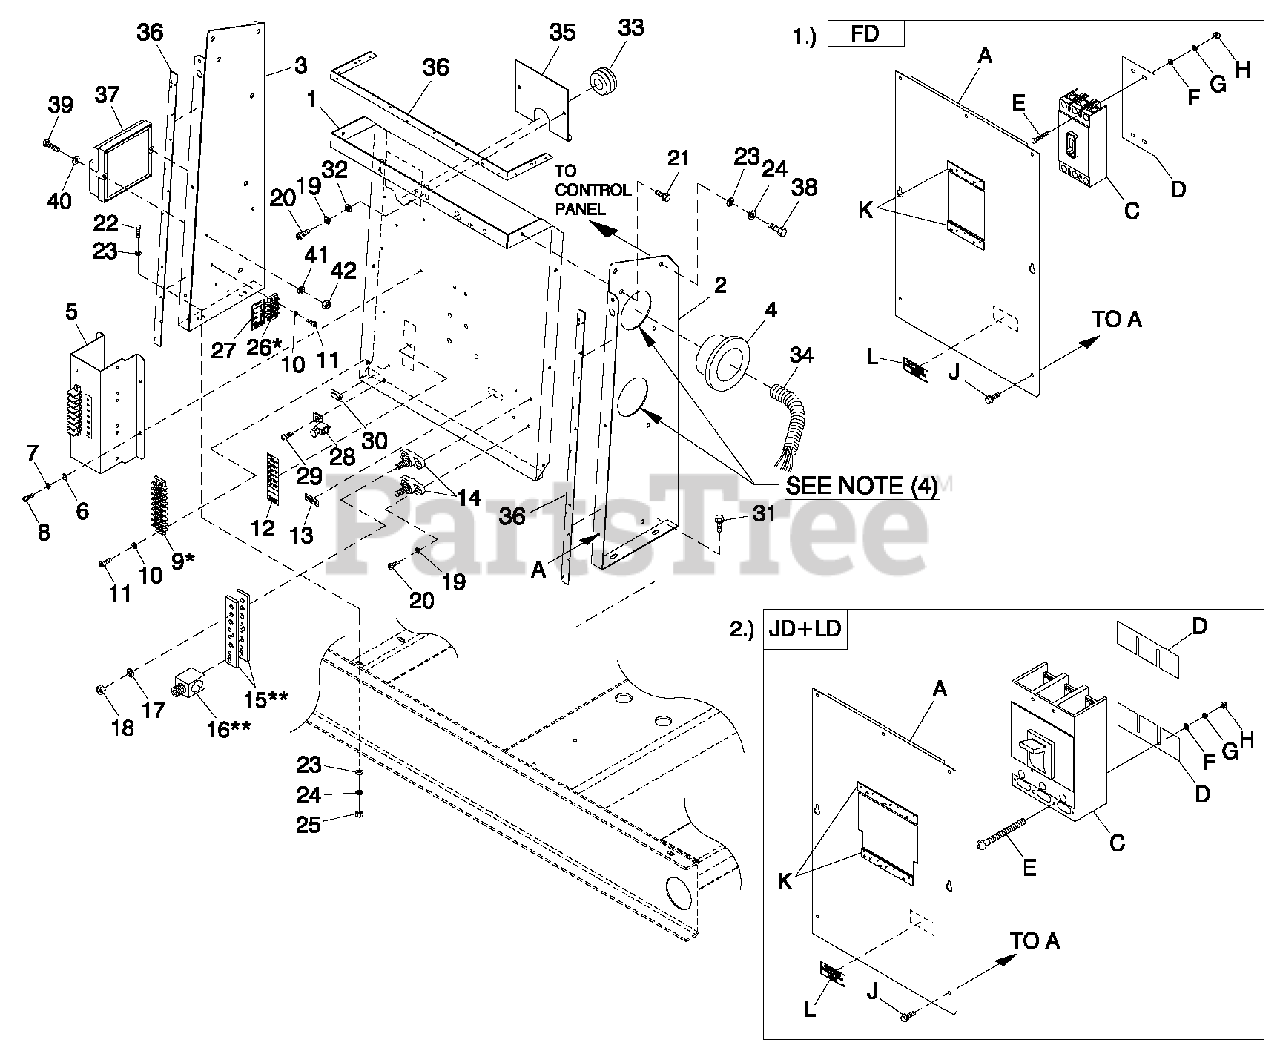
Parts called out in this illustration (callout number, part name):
1	PANEL CB CONN BOX
1	UL CIRCUIT BREAKER (FD)
2	STAND RH CONTROL
2	UL CIRCUIT BREAKER (JD+LD)
3	STAND LH CONTROL C5 GRBX
4	BUSHING SNAP SB-2.5-31
5	ASSY PCB INTERFACE 1PH 240V
6	WASHER FLAT M4
7	WASHER LOCK #8-M4
8	SCREW PHTT M4-0.7 X 10 ZYC
9	BLOCK TERM 20A 8 X 6 X 1100V
10	WASHER LOCK #6
11	SCREW PHTT #6-32 X 1/2 ZYC
12	DECAL CPL CUST CONN H CTRL
13	DECAL NEUTRAL
14	JUNCTION BLOCK 3/8-16
15	BUS BAR NEUTRAL BLOCK 390
16	LUG SLDLSS 600/250-1/0 X 1/4-28
17	WASHER LOCK 3/8
18	NUT HEX 3/8-16 STEEL
19	WASHER LOCK M5
20	SCREW PHTT M5-0.8 X 16 ZYC
21	SCREW THF M6-1 X 16 N WA Z/JS
22	SCREW HHC M6-1.0 X 20 G8.8
23	WASHER FLAT 1/4-M6 ZINC
24	WASHER LOCK M6-1/4
25	NUT HEX M6 X 1.0 G8 YEL CHR
26	BLOCK TERM 20A 6 X 3 X 1100V
27	DECAL CUST CONN 120V UTILITY
28	LUG SLDLSS #6-14 X 13/64 CU
29	SCREW HHTT #10-32 X 3/8 CZ
30	DECAL GROUND LUG
31	SCREW HHTT M6-1.0 X 16 ZYC
32	WASHER FLAT M5
33	GROMMET 1.25 X .25 X .75
34	CONDUIT FLEX 2.0" ID
35	PLATE WIRE SNGL GALV
36	TAPE ELEC 1/2 FOAM (AS REQ'D)
37	ASSY PCB 4.6L IGNITION MODULE
38	SCREW HHC M6-1.0 X 16 G8.8
39	SCREW PPHM #10/32 X 2
40	WASHER FLAT #10 ZINC
41	WASHER LOCK #10
42	NUT HEX #10-32 STEEL
A	COVER FD FRM CB
C	CB 0150A 3P 600V S FD6 LL
D	INSULATOR CB FD FRAME 30MIL
E	SCREW SHC 1/4-20 X 4 G8.8 NZ
F	WASHER FLAT 1/4-M6 ZINC
G	WASHER LOCK M6-1/4
H	NUT HEX 1/4-20 STEEL
J	SCREW THF M6-1 X 16 N WA Z/JS
K	TAPE ELEC 1/2 FOAM (AS REQ'D)
L	DECAL CUSTOMER CONNECT INSIDE
A	COVER CIR BRKR JD/LD
C	CB 0300A 3P 600V S JD6 LL
D	INSULATOR CIRCUIT BR. JD/LD
E	SCREW RHM 1/4-20 X 3
